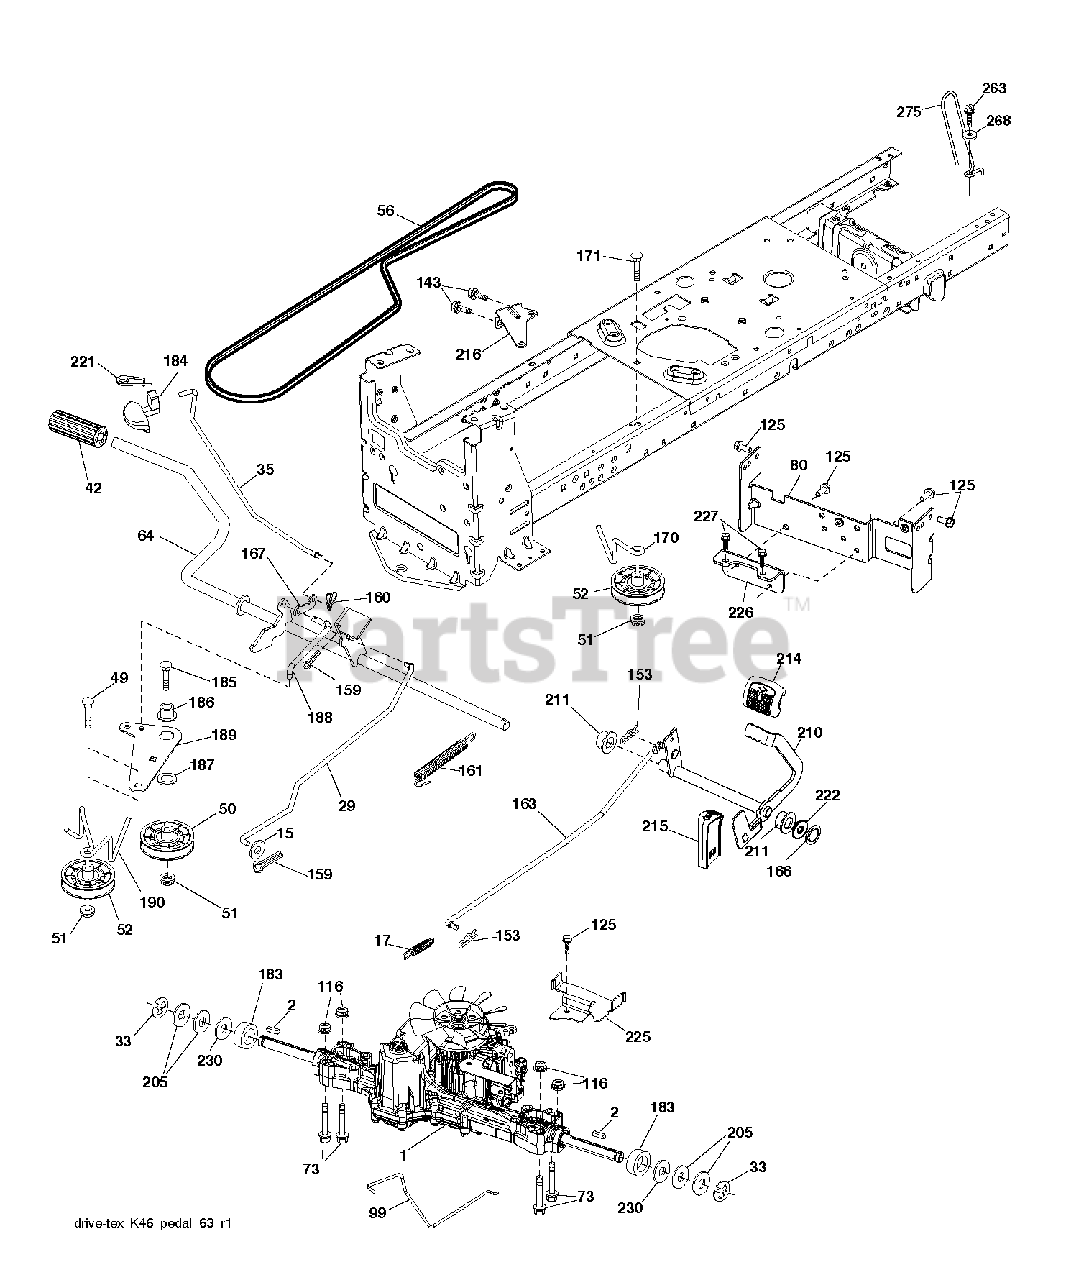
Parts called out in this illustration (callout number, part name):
17	SPRING.BRAKE.K46.GREEN
29	ROD.BRAKE.K46
35	ROD, BRAKE, PARK
42	PEDAL COVER T
49	BOLT
50	IDLER.FLAT.910.OFFSET
51	NUT LOCK FLG 3/8-16 UNC
52	IDLER.V-GROOVE.910.OFFSET
64	SHAFT.ASM.PEDAL.BRK.CNTR
80	STRAP TORQUE
99	ROD.SPRING.BYPASS.K46.LT.Z
116	NUT LOCK HEX FLANGE 5/16-18
125	SCREW
153	RETAINER M
159	COTTER PIN
160	RETAINER CLIP
161	SPRING, RETURN LT
163	ROD.CONTROL.PEDAL.K46
166	NUT.PUSH.625
167	LATCH.BRAKE.SPRING
170	KEEPER.V-IDLER.CENTER.
171	BOLT
184	HANDLE PARKING BRAKE
186	SPACER.RETAINER
187	WASHER 12/32X2X10GA
188	LINK.CLUTCH.GROUND.DRIVE
189	BELLCRANK.GROUND.DRIVE.TEX.
190	KEEPER.BELLCRANK.DRIVE
210	ROCKER.ASM.PEDAL.CONTR
211	BEARING.NYLON
214	PAD PEDAL FORWARD
215	PEDAL.REVERSE.TEX.GT.4
216	BRACKET.PULLEY.IDLER.W/TEX
221	RETAINER.SPRING.CLIP.H
222	WASHER 21/32 X 1-1/4 X 10 GA.
225	KEEPER.BELT.TRANSAXLE.K46
226	BRACKET.MOUNT.TORQUE.K46.TLT
227	SCREW
230	WASHER.HARDENED
263	SCREW, 3/8-16X3/4
268	WASHER
